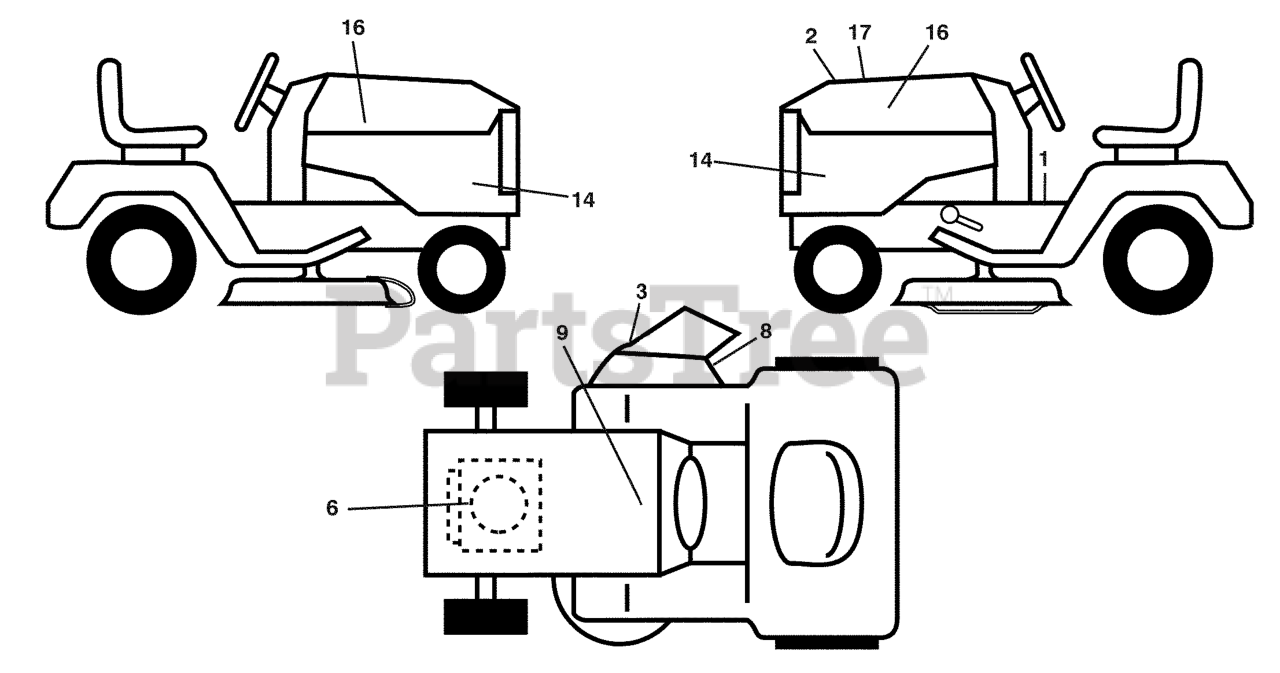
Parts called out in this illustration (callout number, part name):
1	DECAL.FENDER.WARNING.ENG
2	DECAL.WARNING.CUST.RESP.E85.
3	DECAL.WARN.KEEP.HAND.AWAY
6	DECAL, ENG. HP
8	DECAL.MOWER.SCH.48/54
9	DECAL BTRY SYMBOLS
14	DECAL, PANEL SIDE
16	DECAL.HOOD.LOGO.ORANGE.HUSQVAR
